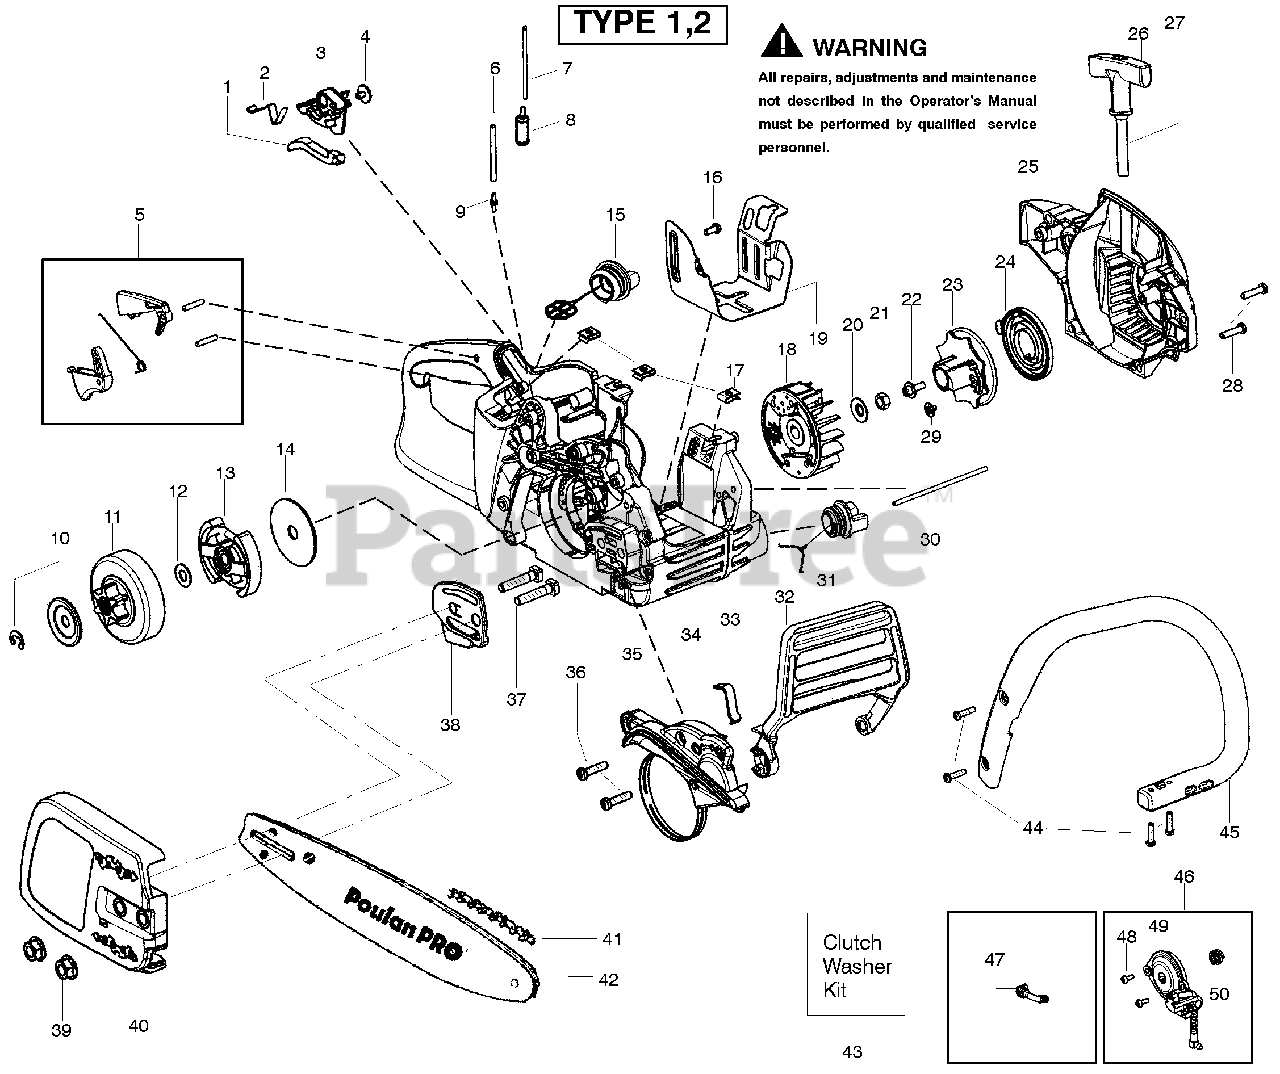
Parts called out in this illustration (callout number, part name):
1	Knob-Choke
2	Spring-Ign. Switch
3	Lever-Ign. Switch
5	Kit-Trigger/Lockout
6	Kit-Fuel Line (Large)
7	Kit-Fuel Line (Small)
8	Assy-Fuel Pick Up
9	Fitting-Fuel line
10	Kit-Clutch Washer
11	Assy-Clutch Drum 3/8"
12	Kit-Clutch Washer
13	Assy-Clutch
14	Washer-Large Clutch
15	Assy-Fuel Cap w/ret
17	Nut-"U" type speed
18	Assy-Flywheel
19	Shield-Heat
20	Washer-Flywheel
21	Nut-Flywheel
23	Pulley-Starter
24	Spring-Starter
25	Housing-Fan
26	Handle-Starter
27	Kit-Rope
30	Assy-Oil Vent
31	Assy-Oil Cap w/ret.
32	Handguard
33	Spring-Handguard
34	Assy-Chassis
35	Kit-Chainbrake
37	Bolt-Bar
38	Plate-Bar
40	Cover-Clutch
41	Accy-16" Chain
42	Accy-16" Bar
43	Kit-Clutch Washer
45	Handle-Front
46	Kit-Oil Pump
47	Assy-Oil Pick Up
49	Assy-Oil Pump
50	Gear-Worm
